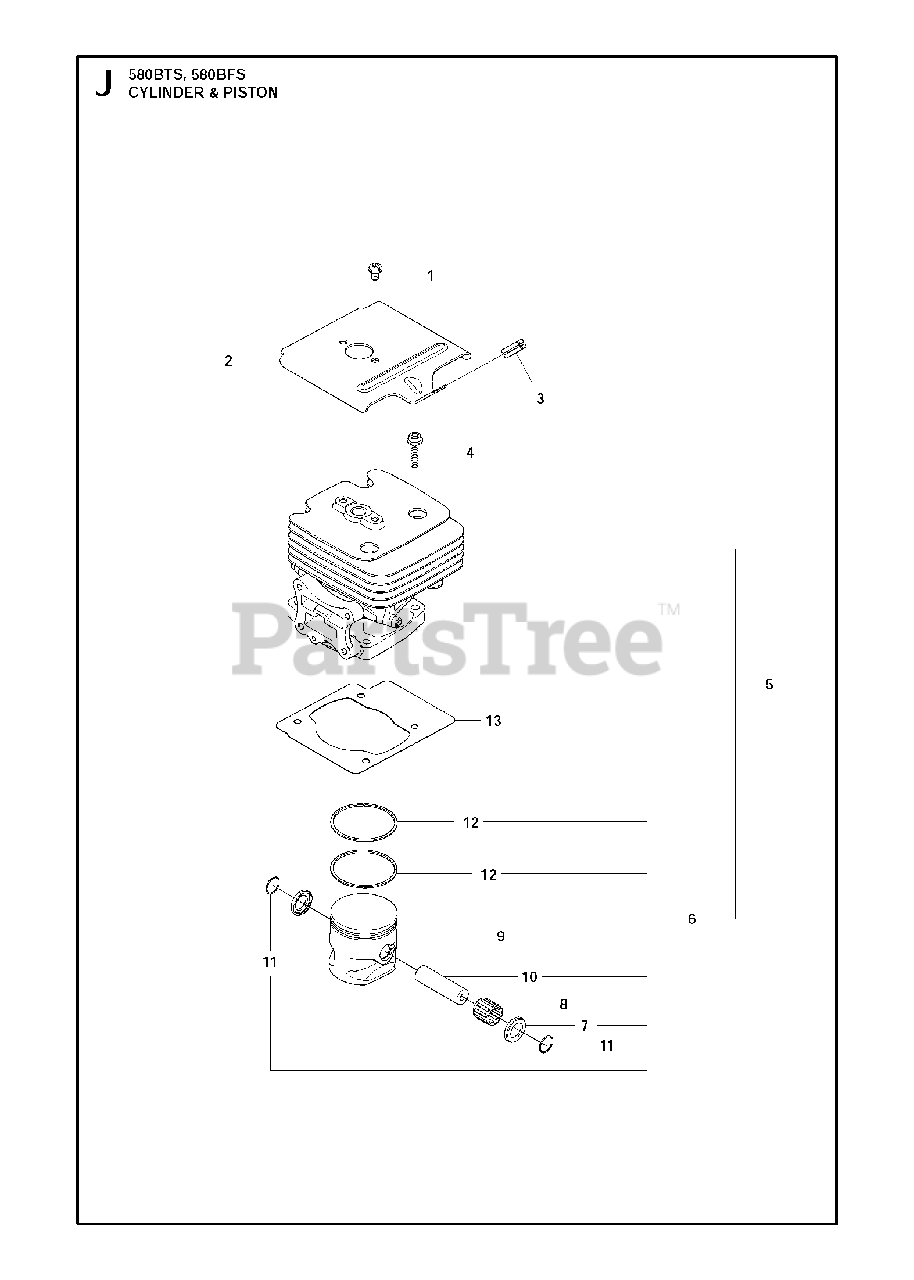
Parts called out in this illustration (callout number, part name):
5	CYLINDER ASSY
6	PISTON
7	WASHER
8	BEARING
9	PISTON
10	PISTON PIN
11	SNAP RING
12	PISTON RING
